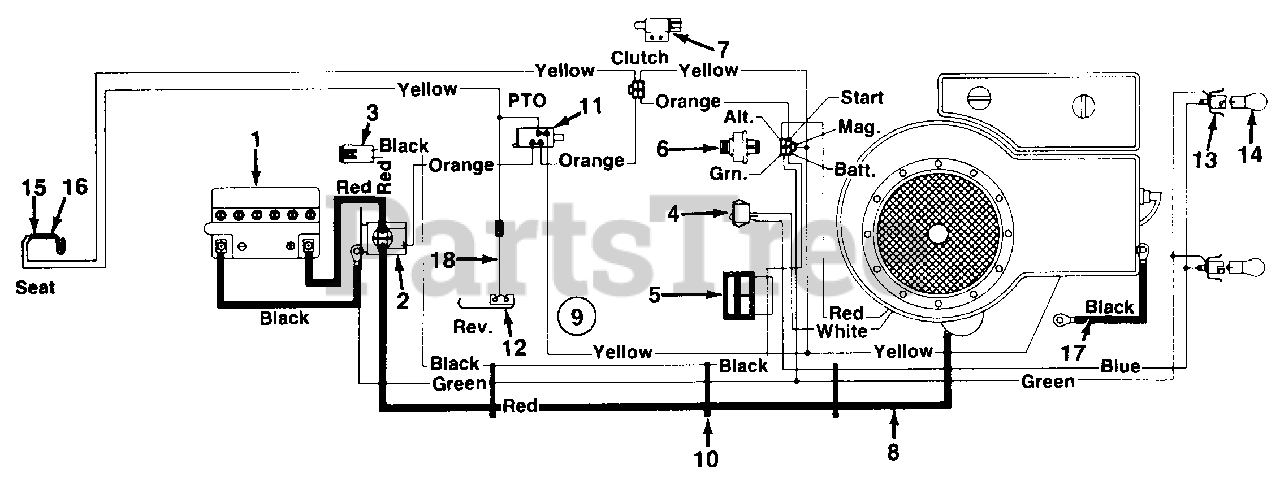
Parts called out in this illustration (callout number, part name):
1	Battery
2	Solenoid
3	Fuse 7'/2 Amp
4	Light Switch
5	Ammeter
6	Ignition Switch
7	Safety Switch (Clutch)
8	Electric Wire 30" Lg.
9	Wire Harness
10	Cable Tie
11	Safety Switch (Deck)
12	Safety Switch (Reverse)
13	Socket
14	Bulb
15	Safety Switch (Seat)
16	Safety Switch (Seat)
17	Ground Wire 7.5" Lg.
18	Ext. Wire
